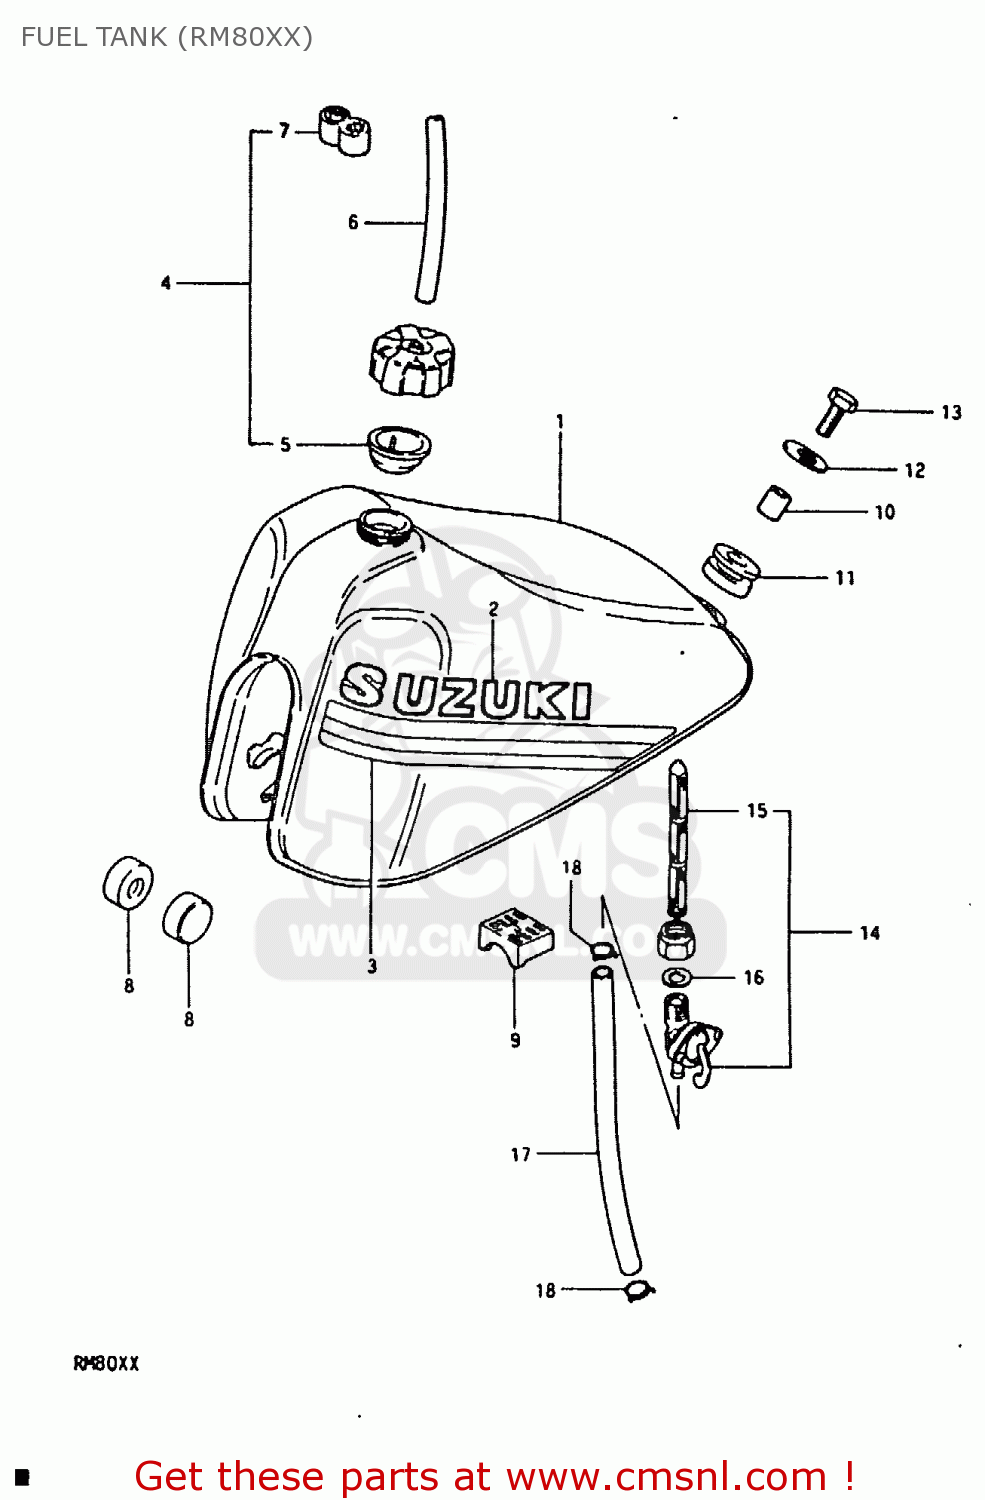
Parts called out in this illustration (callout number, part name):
1	TANK, FUEL (YELLOW)
2	EMBLEM
3	TAPE SET, STRIPING
4	CAP ASSEMBLY,FUEL TANK
5	GASKET,FUEL TANK CAP
6	HOSE
7	CLAMP,FUEL TANK BREATHER HOSE
8	CUSHION
9	CUSHION,FUEL TANK
10	SPACER (8.2X12X17)
11	CUSHION
12	WASHER (8.5X29X1.6)
13	BOLT (8X30)
14	COCK ASSY,FUEL
15	FILTER,FUEL
16	GASKET,FUEL COCK (NAS)
17	HOSE
18	CLIP
